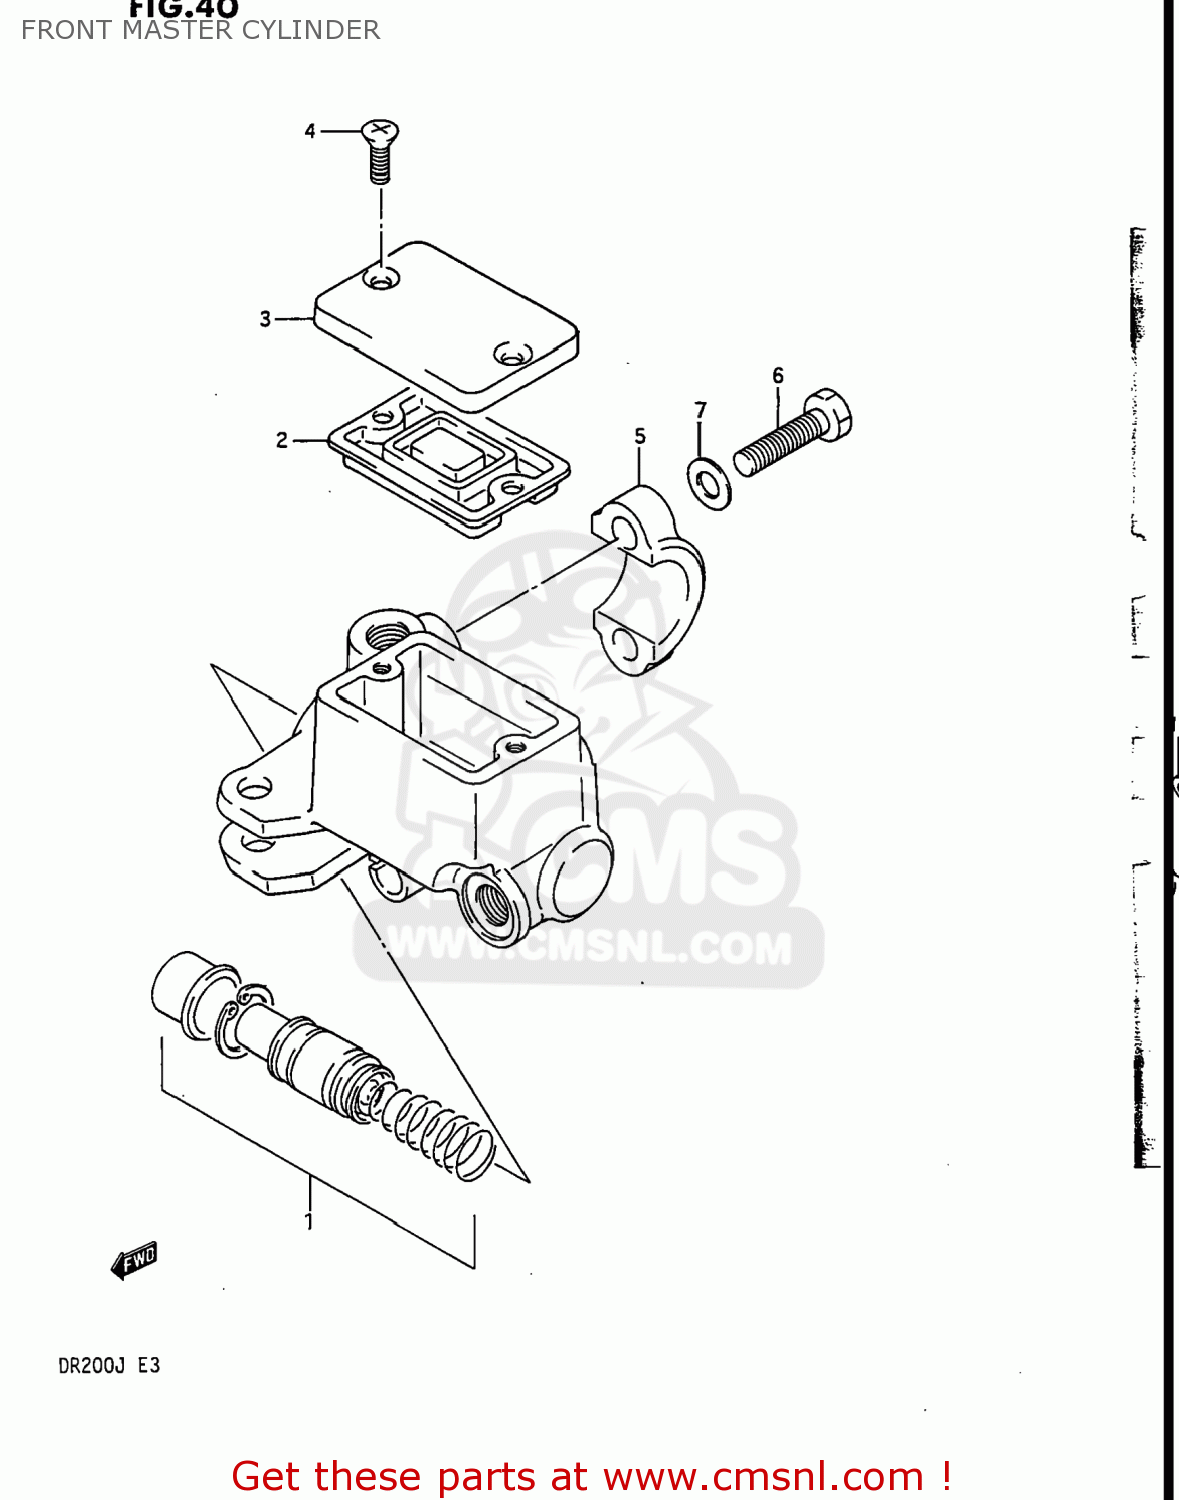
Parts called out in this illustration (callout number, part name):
1	PISTON/CUP SET
2	DIAPHRAGM
3	CAP
4	SCREW
5	HOLDER
6	BOLT
7	WASHER
